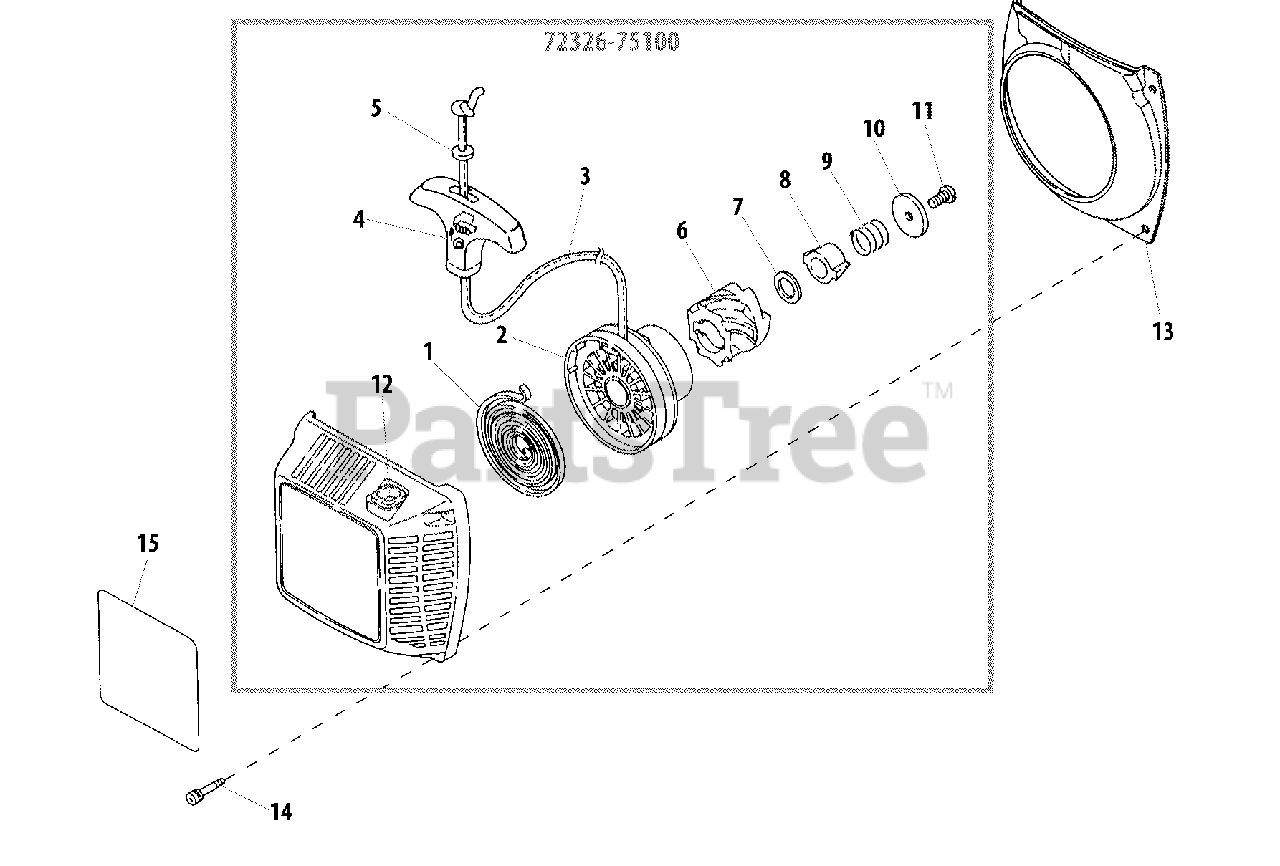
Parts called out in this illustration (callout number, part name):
1	SPRING, REWIND
2	REEL, ROPE
3	ROPE
4	GRIP, STARTER
5	RETAINER, ROPE
6	RATCHET
7	WASHER, THRUST
8	GUIDE
9	SPRING, FRICTION
10	WASHER
11	SCREW
12	GUIDE, ROPE
13	DEFLECTOR, AIR
14	SCREW - 4X20
15	LABEL - MODEL
72326-75101	STARTER ASSY
